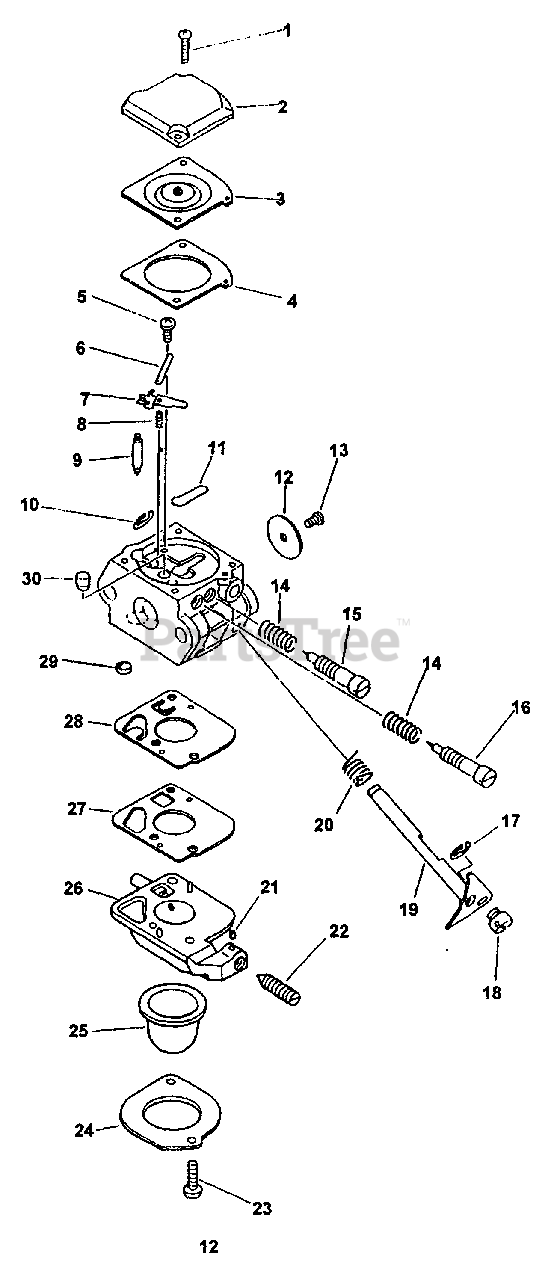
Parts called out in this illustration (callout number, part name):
2	COVER, METERING
3	DIAPHRAGM, METERING
4	GASKET, METERING
5	SCREW, METERING LEVER PIN
6	PIN
7	LEVER, METERING
8	SPRING, METERING LEVER
9	VALVE, NEEDLE
10	RING, RETAINING
11	PLUG, WELCH
12	VALVE, THROTTLE
15	NEEDLE - LOW SPEED
16	NEEDLE - HIGH SPEED
17	RING, RETAINING
19	SHAFT, THROTTLE
20	SPRING, RETURN
21	PIECE, FRICTION
22	SCREW, IDLE ADJUST
23	SCREW, RETAINER
24	RETAINER, PURGE BULB
25	BULB, PURGE
26	BASE, PURGE
27	GASKET, PURGE
28	DIAPHRAGM, PURGE
29	STRAINER
30	NOZZLE, CHECK VALVE
